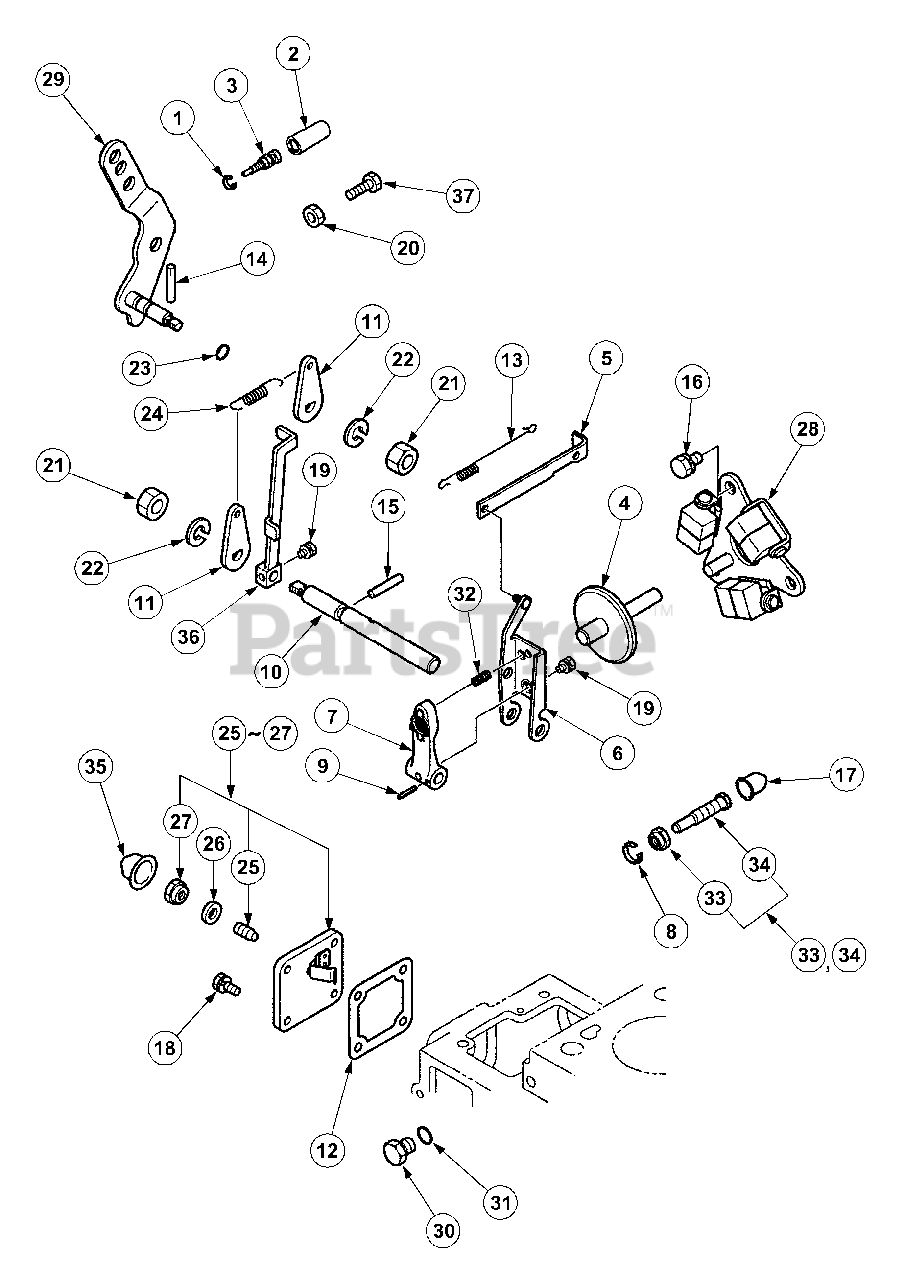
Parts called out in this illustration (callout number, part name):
6	Lever Assy,Governor
7	Lever,Tension
9	Pin,Spring
10	Shaft,Governor
11	Lever,Governor
12	Gasket,Tie Rod
13	Spring,Tie Rod
14	Pin,Governor
15	Pin,Governor
16	Bolt,w/Washer
18	Bolt,w/Washer
19	Bolt,w/Washer
22	Washer,Spring
24	Spring,Governor
25	Screw,Adjusting
27	Nut,Special
28	Weight Assy,Governor
29	Lever Assy,Speed
34	Screw,Pack Set
35	Cap,Sealing
36	Lever,Tor Set
